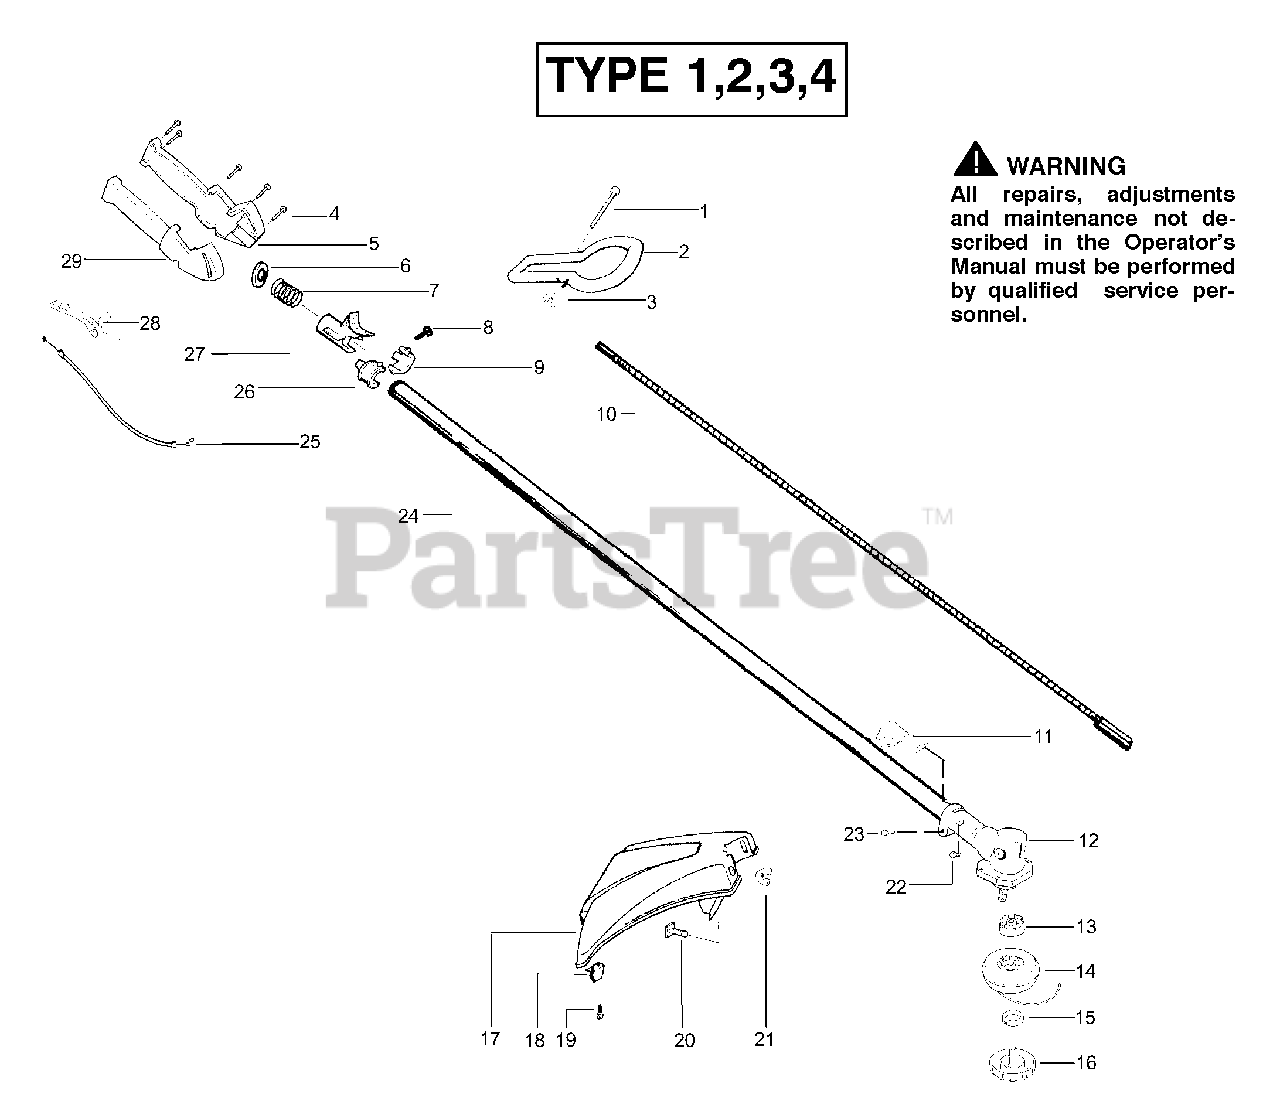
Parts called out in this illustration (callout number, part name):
1	Bolt-Handle
2	Handle-Assist
3	Wingnut
5	Hsg.-Throttle (Left)
7	Spring-Compression
8	Screw
9	Locator-left
10	Drive Shaft - Flex
11	Bracket-Shield
12	Assy-Gearbox
13	Dust Cup
14	Assy. - Wound Hub
15	Guide - Line
16	Assy. - Cap 3/8"
17	Kit-Shield Ass'y.
18	Line Limiter
19	Screw-Line Limiter
20	Bolt-Shield
21	Wingnut
24	Assy-Drive Shaft Hsg.
25	Assy-Throttle Cable
26	Locator-right
27	Actuator
28	Trigger - Throttle
29	Throttle Hsg. (Right)
